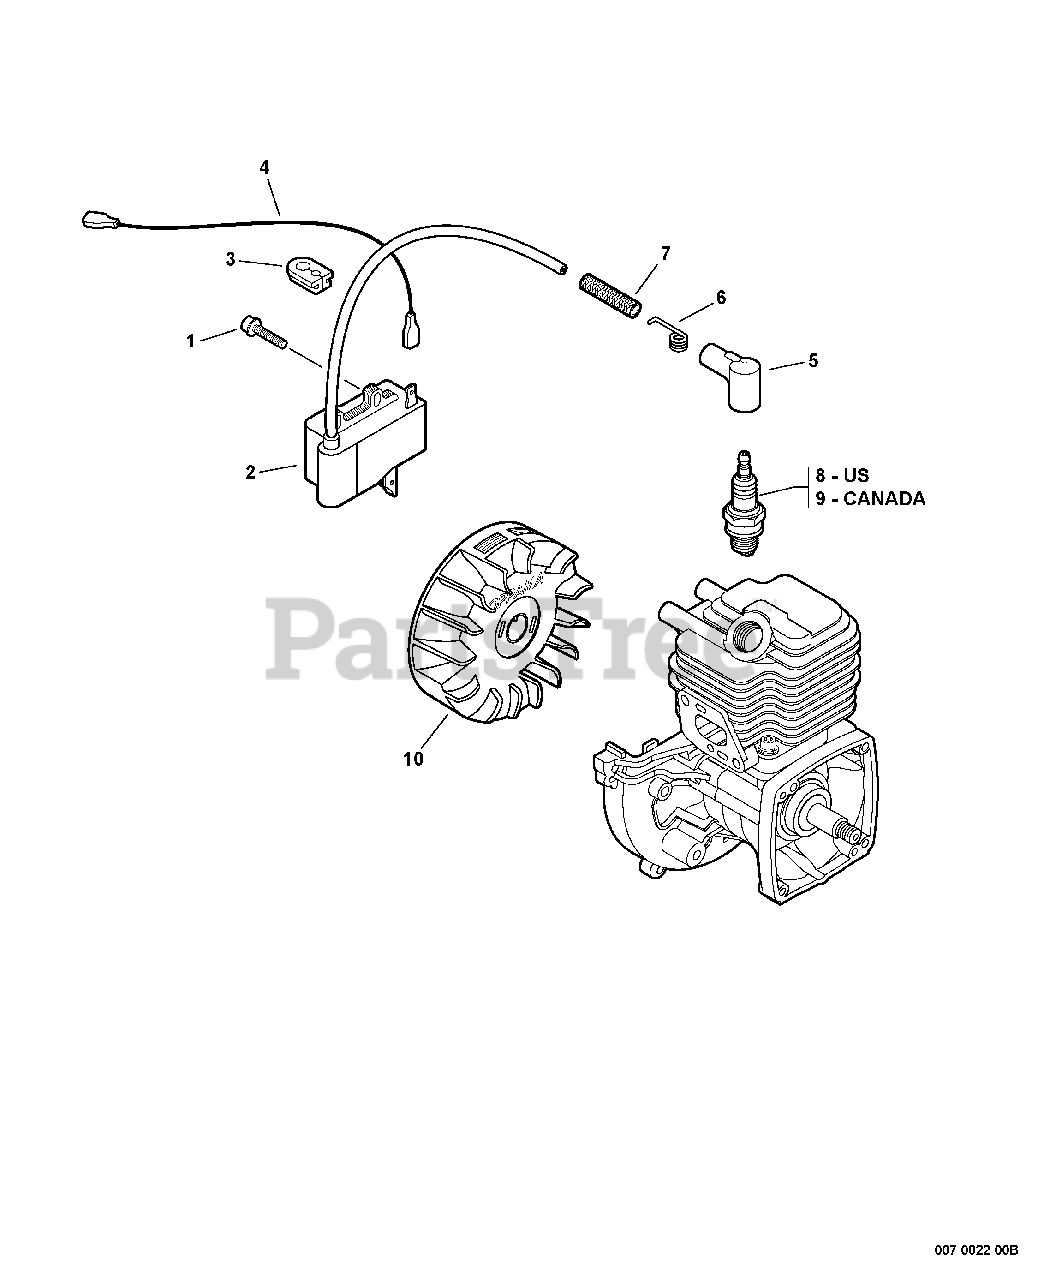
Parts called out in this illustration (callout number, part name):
1	BOLT 4×20
2	COIL, IGNITION
4	LEAD
5	CAP, SPARK PLUG
6	TERMINAL, SPARK PLUG
7	TUBE, INSULATOR
8	SPARK PLUG - BPM8Y
9	SPARK PLUG - BPMR8Y
10	FLYWHEEL
